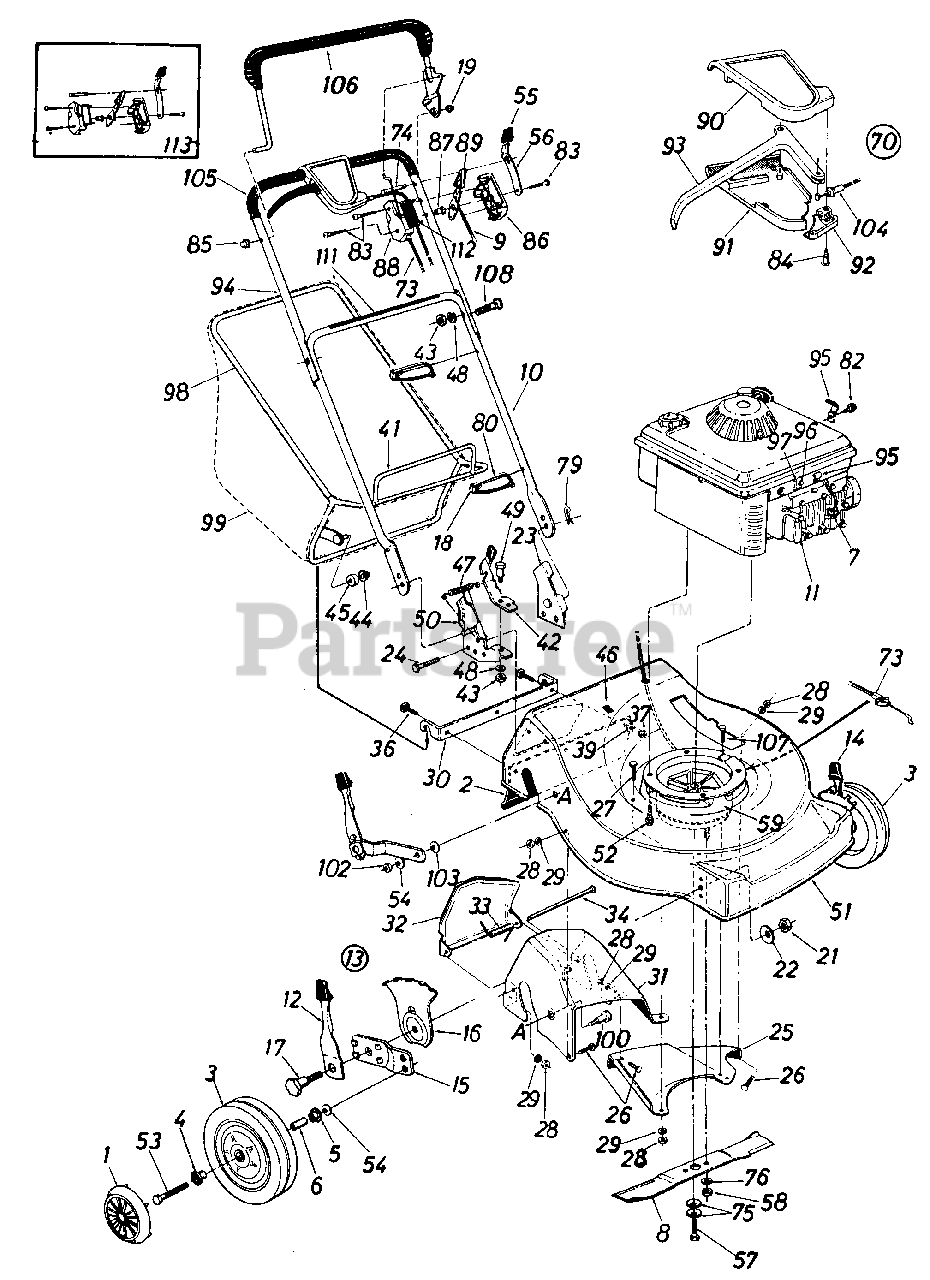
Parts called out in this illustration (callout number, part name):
3	WHEEL ASSY W/TIRE-8X1.75
4	BEARING-FLANGE
5	BEARING-BALL
7	INSULATOR-SPARK PLUG
8	BLADE-22IN BBC
9	WIRE-THROTTLE 58 LG
10	HANDLE-LOWER PAINTED
12	LEVER & KNOB ASSY
13	ADJUSTER ASSY-HGT-RH
14	ADJUSTER ASSY-HGT-LH
15	BAR-PIVOT R
16	PLATE-HGT ADJ R
17	SCREW-SHLD R
18	TIE-CABLE
21	NUT-HEX 3/8-16
22	WASHER-BELL .390 ID X 1.375 X .062
23	BRACKET ASSY-HDLE
24	SCREW-HEX L-WASH HD
25	BAFFLE-CHUTE-RR-LH
26	BOLT-CARRIAGE 1/4-20 X .50
27	SCREW-HEX 1/4-20 X .88
28	NUT-HEX 1/4-20
29	LOCK WASHER 1/4 DIA
30	ADAPTER-GRASSCATCHER
31	BAFFLE-CHUTE-RR-RH
32	DOOR-CHUTE
33	SPRING-TORSION
34	PIN-HINGE
36	BOLT-CARRIAGE 1/20 X .75
37	NUT-SEMS 1/4-20
39	WASHER-FL-.285 ID X 1.25 OD X .060
43	NUT-HEX 5/16-18
45	ROLLER-PLASTIC
47	SPRING-EXTENSION
48	WASHER-LOCK-5/16
49	SCREW-SHLD .437 DIA X .162
50	BRACKET ASSY-HDLE
51	DECK ASSEMBLY-22IN-RD
52	SCREW-HEX R
53	SCREW-HEX 3/8-16 X 1.75
54	WASHER-BELL .400 ID X .88 X .060
55	KNOB
56	SPRING-LOCKOUT
57	SCREW-HEX 3/8-24 X 2.00
58	NUT-HEX 3/8-24
59	CLUTCH ASSY-BLADE
70	KIT-CLUTCH CONTROL
73	CABLE-CLUTCH
74	PIN-LOCKING
75	WASHER-BELL .400 ID X .88 X .060
76	WASHER-LOCK-3/8
79	PIN-INTERN COT-5/16 DIA
80	TIE-CABLE
82	SCREW-HEX B-TAP #10 X .38
83	SCREW-TRUSS MACH
84	SCREW-FL C-SUNK AB
85	NUT-SPEED
86	PANEL HALF-CLUTCH
86	PANEL HALF-CONTROL
87	PIN-CONTROL DISC
88	PANEL HALF-CLUTCH
89	LEVER-THROTTLE CONT-REV
90	COVER-HALF-CONTROL
91	COVER-HALF CONT-LWR
92	CAP-CABLE MTG
93	LEVER-CONTROL
94	HANDLE-UPPER-CHROME
95	CLAMP-CASING
96	SCREW-HEX WASH HD TAP
97	CLAMP-CASING
98	FRAME-CATCHER-UPR
99	BAG-GRASS
100	SCREW-SHLD .500 DIA X .685
102	NUT-HEX JAM 3/8-18
103	WASHER-BELL .3/8ID X 1.12OD X .030
104	CABLE-CLUTCH
105	GRIP-SHRINK-25 IN
107	SCREW-HEX HD TAP 1/4-20 X 7.5
108	BOLT-CARRIAGE-CURV 5/16-18 X 1.38
111	LABEL-BBC-INST
113	HARDWARE PACK
